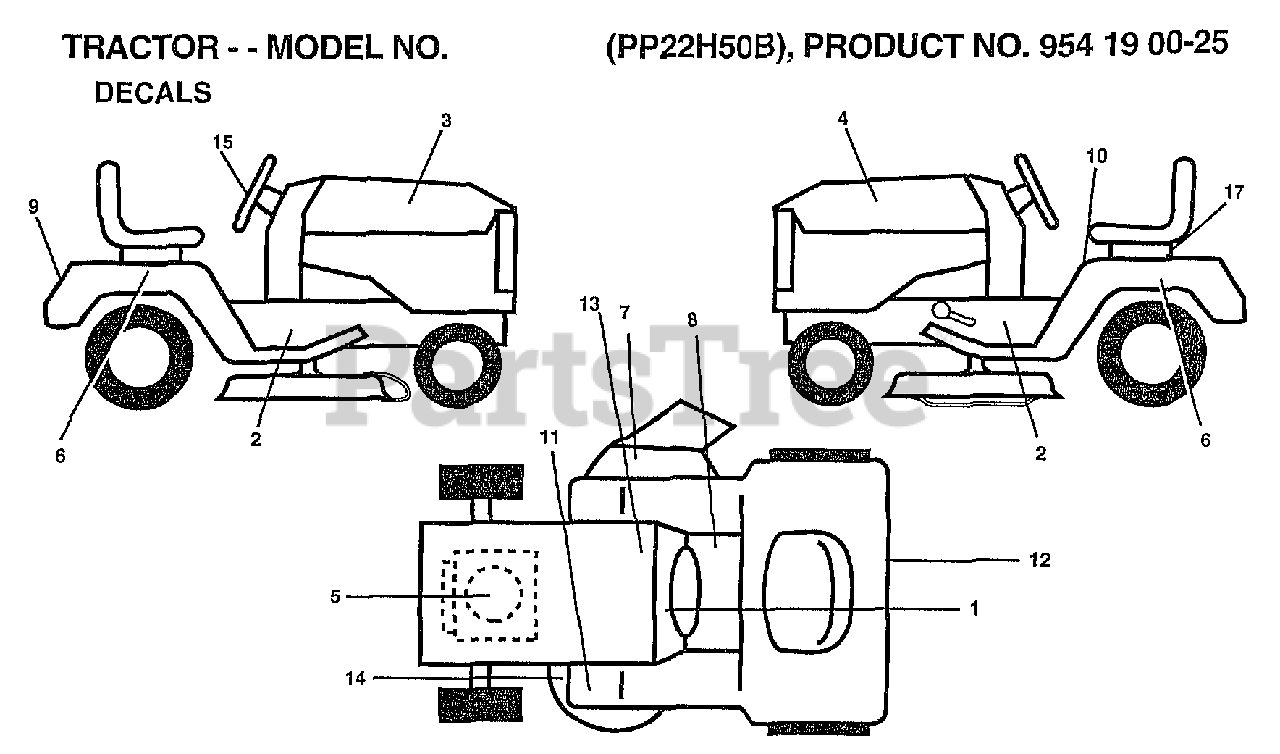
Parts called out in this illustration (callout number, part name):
1	"DECAL-INST,OPER"
2	"DECAL.CHASSIS.50"""
3	DECAL.HOOD.RH
4	DECAL.HOOD.LH
5	DECAL/D-BAR CTRL MVT HYD YT/GT
6	DECAL.FENDR.AUTO
7	"DECAL, WARNING"
8	DECAL BRAK PARK
9	DECAL.FENDER.BELT.GUARD
10	DECAL.CAUT.ENG/FR
11	DECAL T
12	DECAL D-BAR CNTRL
13	DECAL.BATRY.3-3908
15	DECAL INS STRG WH
17	RETAINER-SPRING
